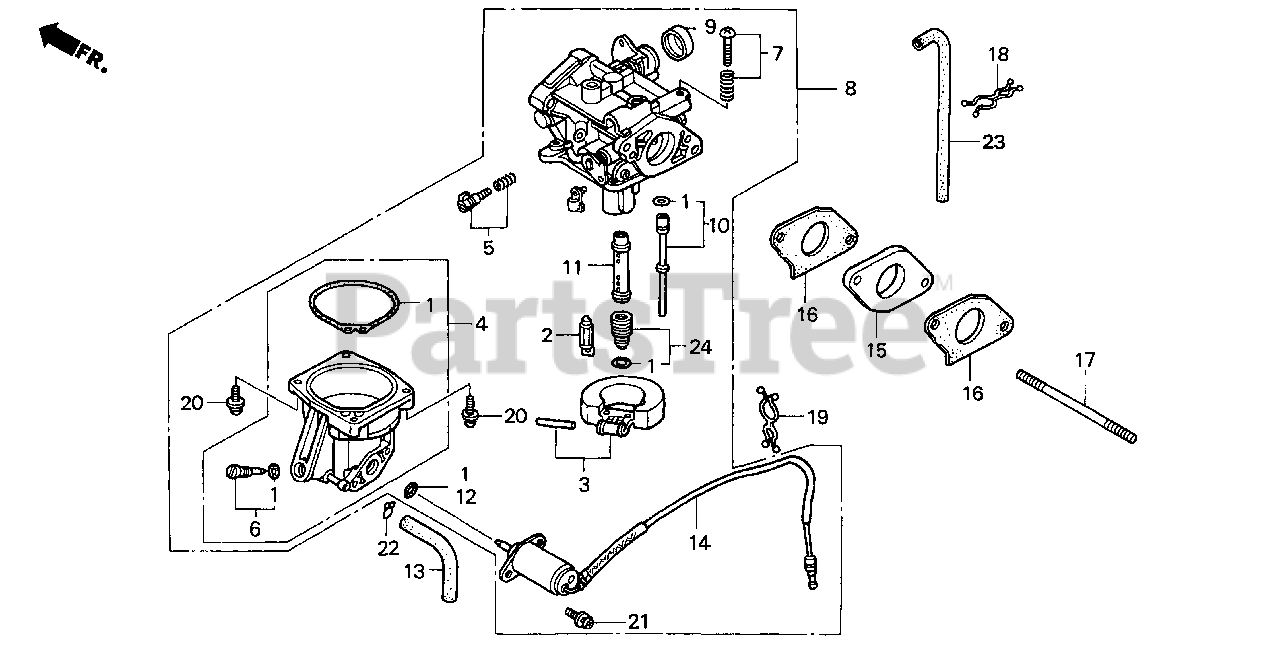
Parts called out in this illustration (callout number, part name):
1	GASKET SET
2	VALVE SET, FLOAT
3	FLOAT SET
4	CHAMBER SET, FLOAT
5	SCREW SET
6	SCREW SET, DRAIN
7	SCREW SET
8	CARBURETOR ASSY. (BG23B A)
9	CAP, CHOKE LEVER DUST
10	JET SET (#42)
11	NOZZLE, MAIN
12	O-RING (5.8X1.9)
13	TUBE, DRAIN
14	VALVE ASSY., SOLENOID
15	INSULATOR, CARBURETOR
16	GASKET, CARBURETOR
17	BOLT, STUD (6X100)
18	CLIP, WIRE HARNESS
19	CLIP, PURSE LOCK
20	SCREW-WASHER (4X14)
21	SCREW-WASHER (5X12)
22	CLIP, TUBE (B8)
23	BULK HOSE, VACUUM (4.5X1000) (4.5X540)
24	JET SET, MAIN (#102)
24	JET SET, MAIN (#105)
24	JET SET, MAIN (#108)
